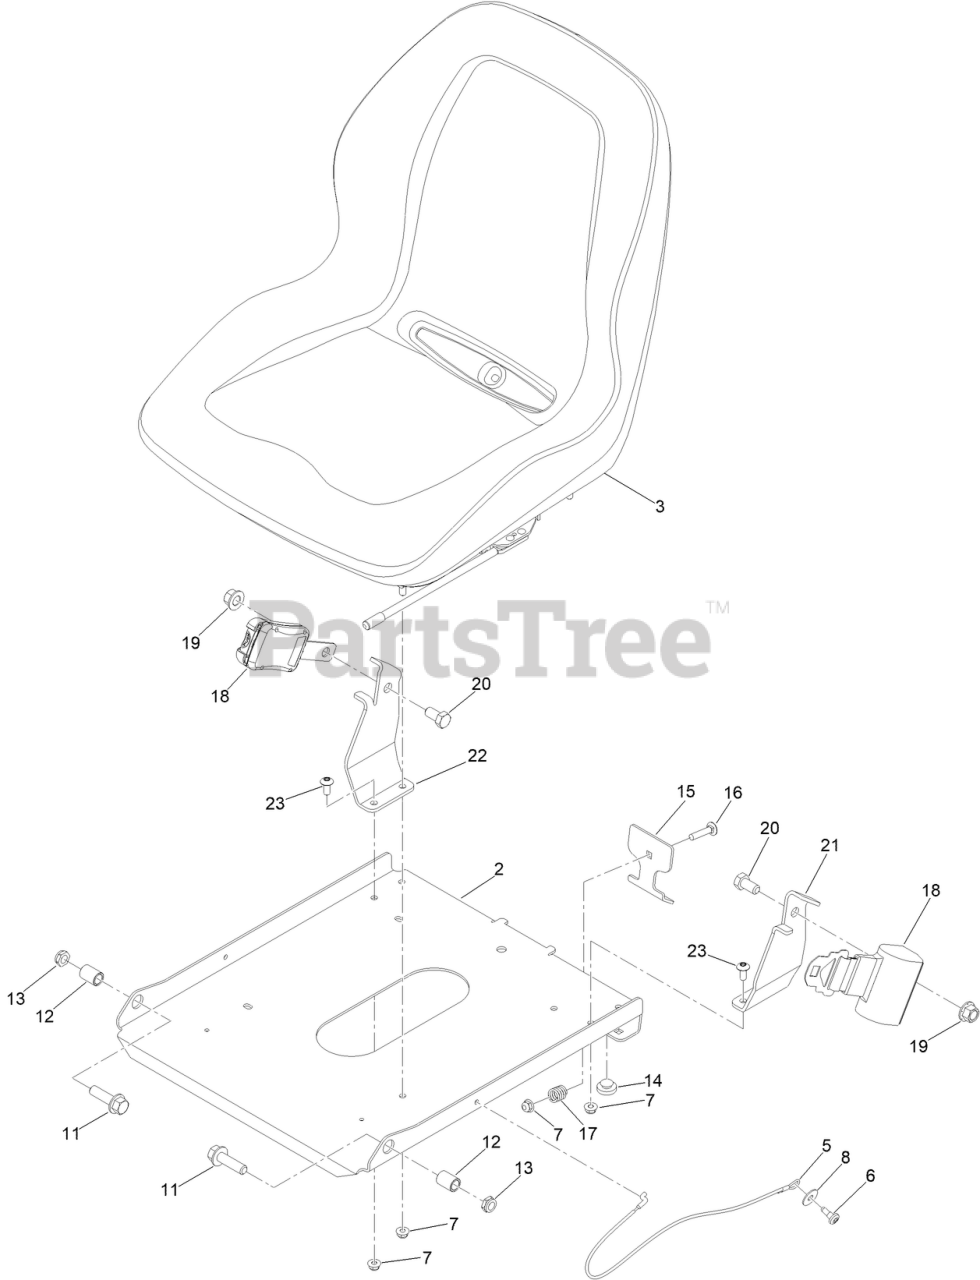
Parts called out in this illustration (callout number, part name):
2	PAN-SEAT, LOWERED
3	BUSHRANGER RT SEAT
5	CABLE-LANYARD
6	SCREW-SHOULDER
7	NUT-HF
8	WASHER-FLAT
11	SCREW-HHF
12	BUSHING-PIVOT, SEAT
13	NUT-HEX
14	BUMPER-SEAT
15	BRACKET-LATCH, SEAT
16	BOLT-CARR
17	SPRING-COMPRESSION
18	SEAT BELT KIT
19	NUT-HF
20	SCREW-HH
21	BRACKET-SEATBELT, LH
22	BRACKET-SEATBELT, RH
23	SCREW-TORX
